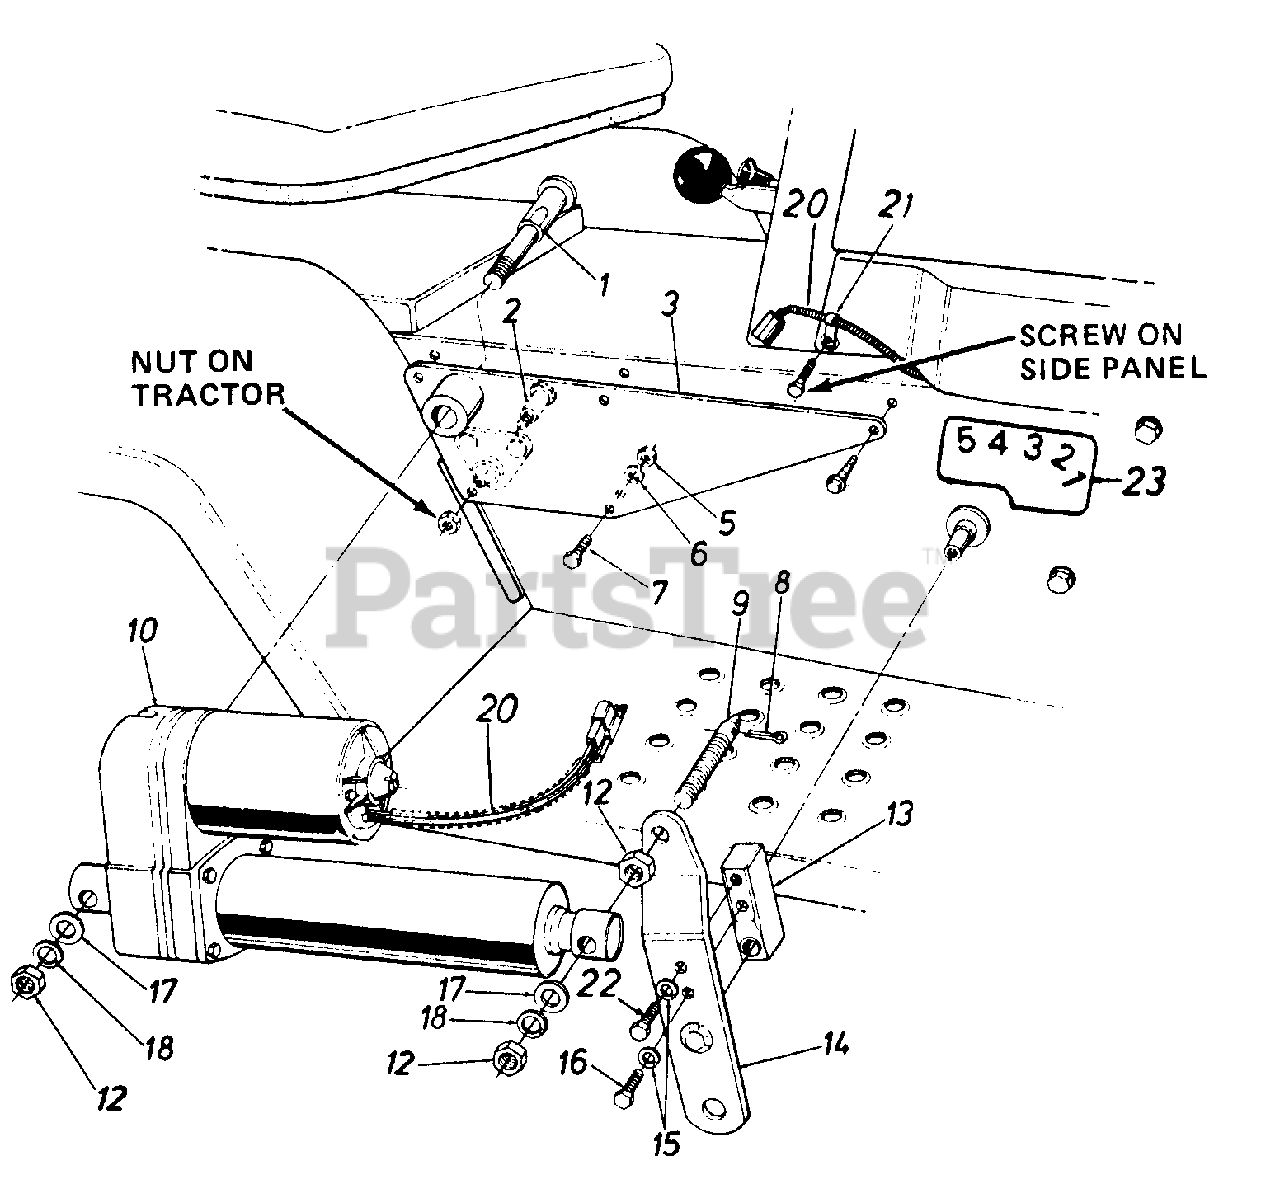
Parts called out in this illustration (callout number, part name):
1	Pivot Pin
2	Shld. Bolt.626 Dia. x .96"
6	L-Wash. 1/4" I.D.*
7	Hex Bolt 1/4-28 x .75" Lg. (Grade 5)
8	Cotter Pin
9	Indicator & Mtg. Pin
10	Electric Actuator
12	Hex Jam Nut 1/2-13 Thd.
13	Lift Shaft Drive
16	Hex Bolt 5/16-24 x 1.0" Lg. (Grade 5)
17	Fl-Wash. .53" I.D. x.93" O.D.
18	L-Wash. 1/2" I.D.*
20	Plastic Tubing-7"
21	Clarnp
22	Hex Bolt 5/16-18 x 1" Lg. (Grade 5)
23	Label
